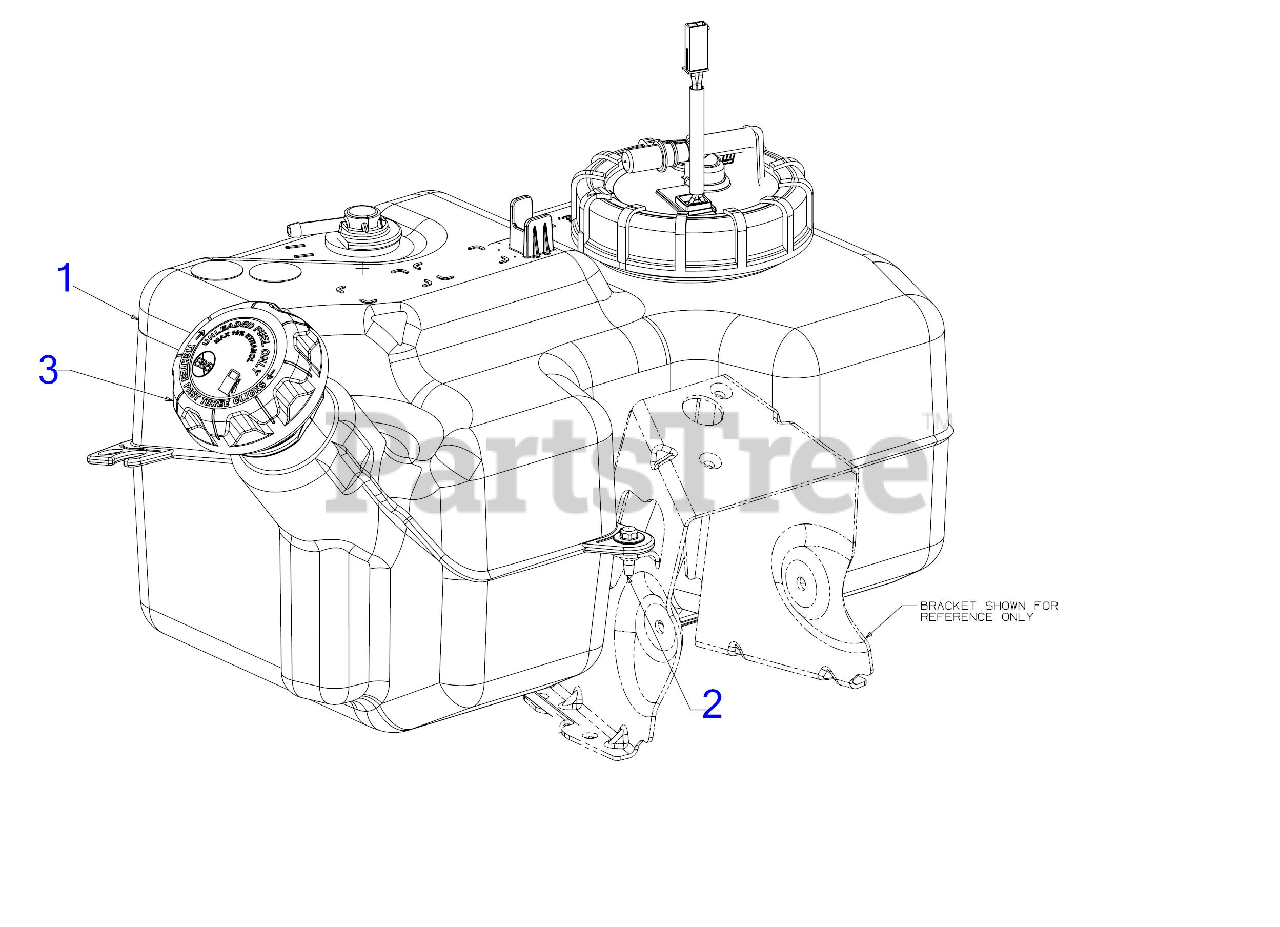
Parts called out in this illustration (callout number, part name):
1	EFI FUEL TANK ASSEMBLY
2	SHOULDER SCREW M6-1 .368 X.115
3	FUEL CAP W/TETHER
